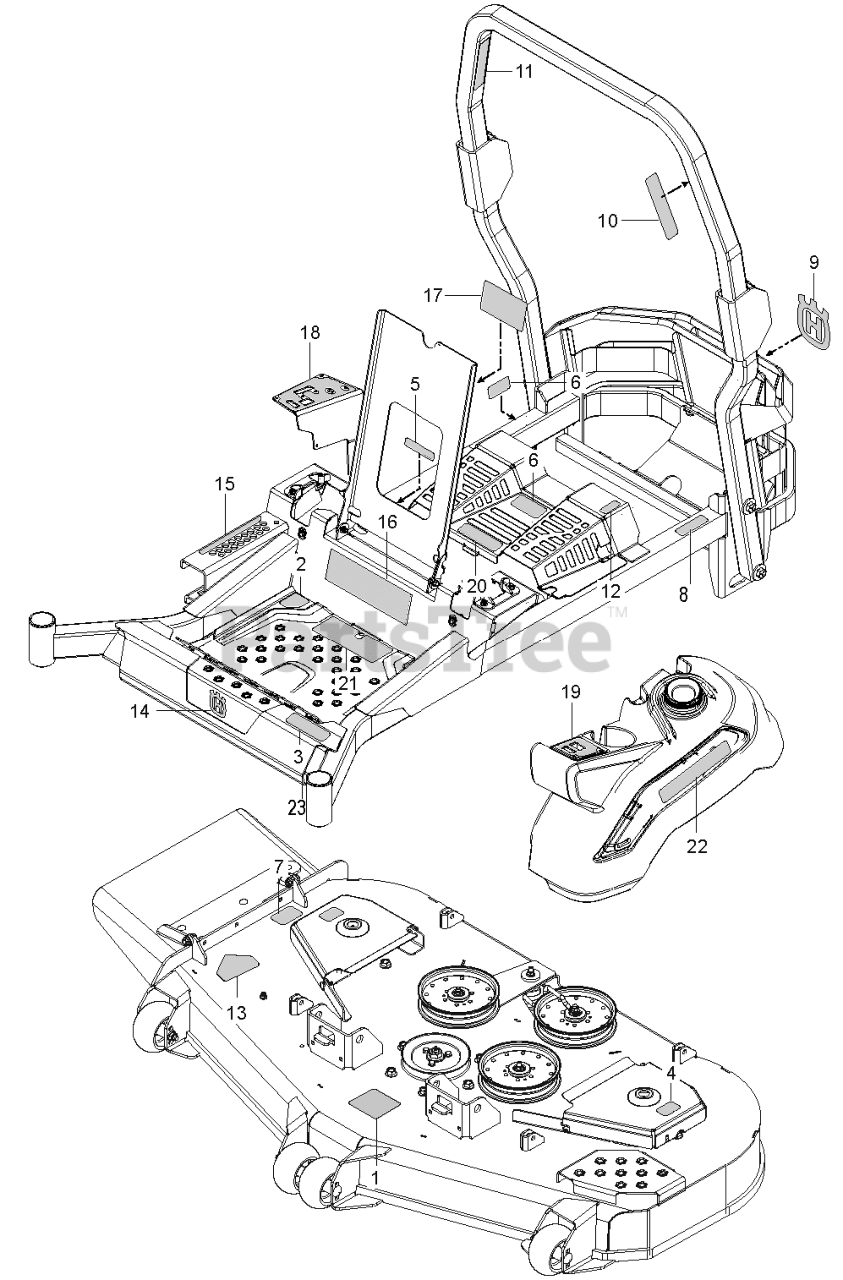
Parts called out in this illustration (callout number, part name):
1	DECAL, BELT ROUTING
1	DECAL, 72" BELT ROUTING
2	DECAL.ZTR.SADLE.WARN.PZ500.ENG
3	DECAL.ZTR.PZ500SERIES.MODEL.Z5
4	DECAL.DECK.6MIL.EURO.NOSTEP
5	EURO DECAL-BATTERY WARNIN6
6	DECAL, BELT DRIVE
7	DECAL.DECK.6MIL./DEF.SHLD.WARN
8	DECAL, WARNING SPARK ARRESTOR
9	DECAL, CROWN H, 110MM
10	DECAL ROPS DECAL DECAL.ROPS.PZ
11	DECAL, ROPS, WARNING
12	DECAL, FUSE
13	DECAL, DECK DEFLECTOR, WARNING
14	DECAL.BADGE.55MM.CROWNH.HUSQ
15	DECAL.PZ500.DECKLIFT.HUSQ
15	DECAL.PZ500.DECKLIFT.CE.HUSQ
16	DECAL.ZTR.SADDLE.COMM.PZ500
17	DECAL.PZ500.MAINTANCE/SVC.2018
18	DECAL.ZTR.CONTRPANEL.PZ500.EFI
19	DECAL.ZTR.CONTROLPANL.PZ500.LH
20	DECAL.ZTR.TRANCOVER.WARN.PZ500
21	DECAL.ZTR.SADLE.WARN.PZ500.ENG
22	DECAL.HUSQVARNA.210MM
23	DECAL.ZTR.PZ500SERIES.Z554X
